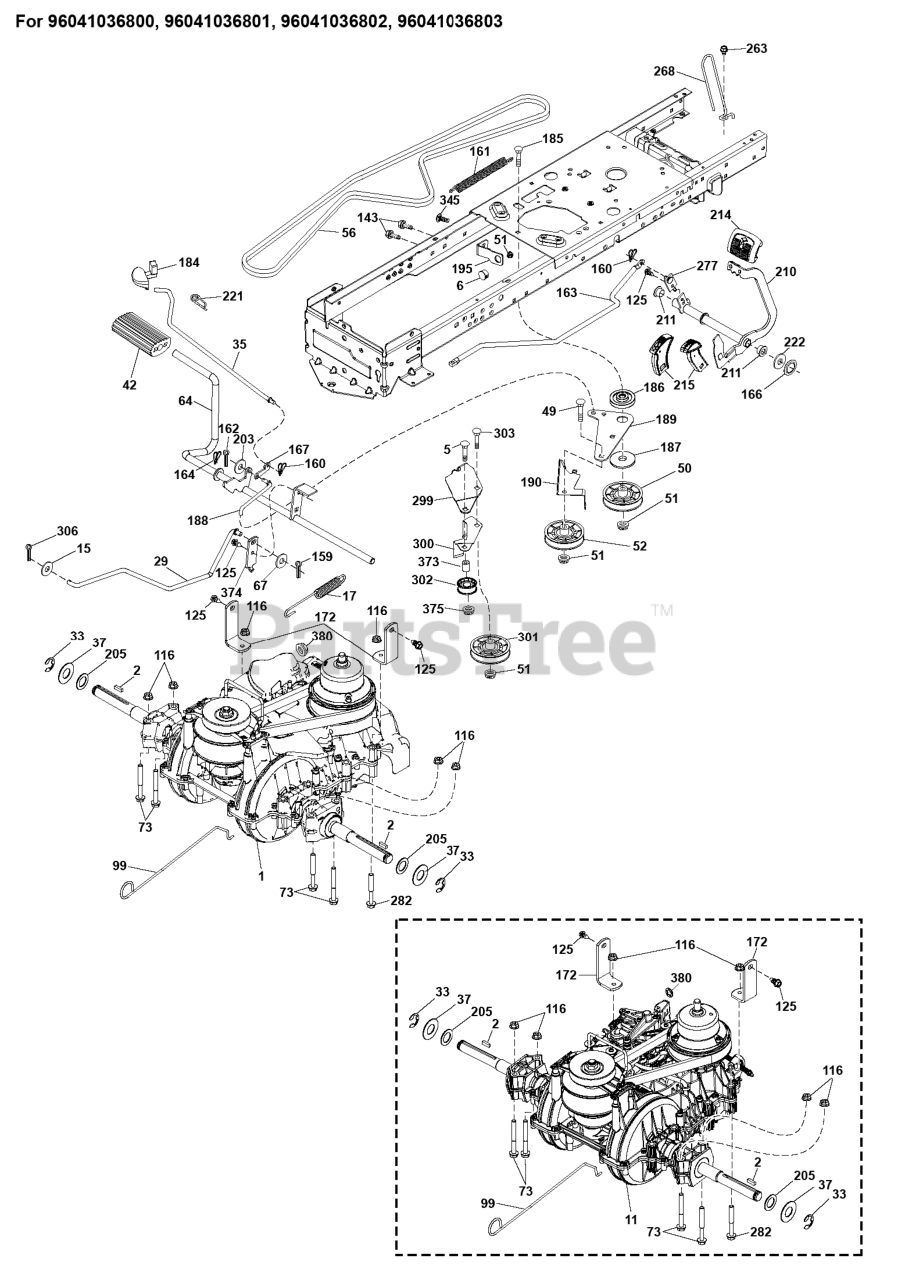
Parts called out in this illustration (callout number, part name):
2	SQUARE KEY
6	BUSHING.SNAP.NYL.BLK.
15	WASHER
17	SPRING.BRAKE.VARIATOR
29	BRAKE.VARIATOR.SD3
35	ROD.CNTRL.PARK.PREDATOR.LT.TEX
37	WASHER.HARDENED
42	PEDAL COVER T
50	IDLER.FLAT.910.OFFSET
51	NUT LOCK FLG 3/8-16 UNC
52	IDLER.V-GROOVE.910.OFFSET
56	BELT.V.EURO.VARIATOR
64	SHAFT VARIATOR PEDAL CROSS
64	SUBASM.SHAFT.PEDAL.BRAKE
67	WASHER.NYLON;13/32X13/16X.109
73	Bolts
99	ROD.BYPASS.VARIATOR.GEN2
116	NUT LOCK HEX FLANGE 5/16-18
125	SCREW
143	Screw 5/16-18 x 1/2 Hex, Self Tapping 5/16-18 x 1/2
159	COTTER PIN
160	RETAINER CLIP
161	SPRING, RETURN LT
162	COTTER PIN
163	ROD.CONTROL.PEDAL.VARIATOR
164	RETAINER CLIP
166	NUT.PUSH.625
167	LATCH.BRAKE.SPRING
172	STRAP.TORQUE.VARIATOR
184	HANDLE.PARKNG BRK.PRED.LT.428
186	SPACER.RETAINER
187	WASHER 12/32X2X10GA
188	LINK.CLUTCH.GROUND DRIVE.LONG
189	BELLCRANK.GROUND.DRIVE.TEX.
190	KEEPER.BELLCRANK.DRIVE
195	BRACKET.BRAKE.BRAKE.VAR.SD
203	WASHER
210	PEDAL.ASM.ROCKET.VARIATOR.LT
210	WELDMENT.PEDAL.VARIATOR
211	BEARING.NYLON
214	PEDAL.FORWARD.PAD.TEX
215	PEDAL.REVERSE.VARIATOR.MS428
215	CAP.PEDAL.REVERSE.VARIATOR
221	RETAINER.SPRING.CLIP.H
222	WASHER 21/32 X 1-1/4 X 10 GA.
263	SCREW, 3/8-16X3/4
268	GUARD MUFFLER
277	SUBASM.LINK.ROCKER.PEDAL
282	BOLT HEX FLGHD 5/16-18X3 GR. 5
299	BRACKET.MOUNT.IDLERS
300	KEEPER.IDLERS.REAR.VARIATOR
301	PULLEY.IDLER.V-GROOVE
302	PULLEY.IDLER.FLAT.2"
303	BOLT CARRIAGE
306	PIN COTTER
373	SPACER.IDLER
374	ARM.CONTROL.BRAKE
380	NUT.FLG.NYLOCK.1/4-20.GR.G.ZY
380	NUT.PUSH.8MM
